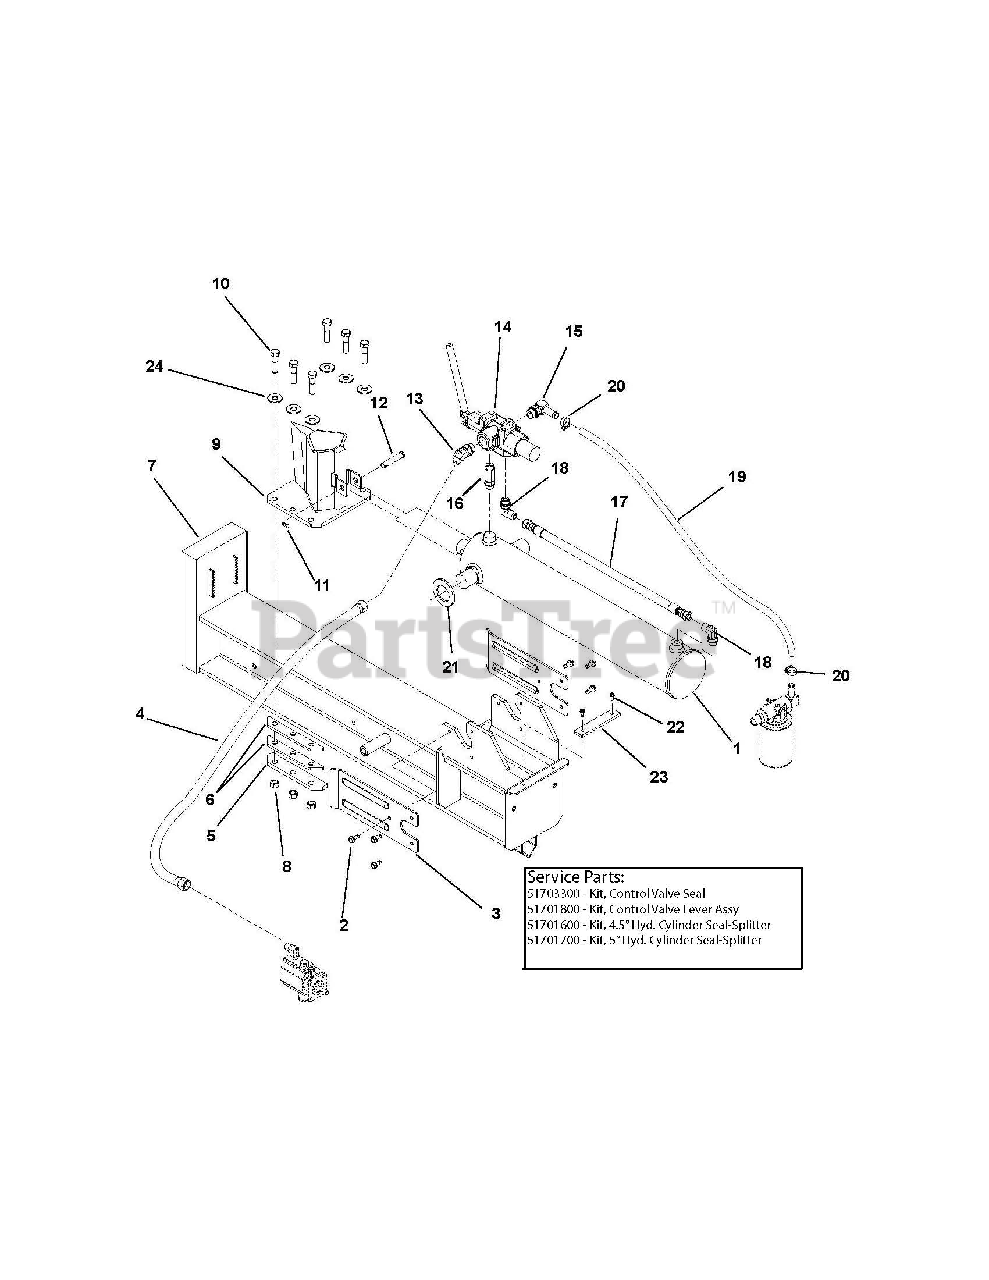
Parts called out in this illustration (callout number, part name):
1	CYLINDER,4.5 W/DECALS
1	KIT,4.5" HYD CYL SEAL-SPLITTER
1	CYLINDER, 5' W/DECALS
1	KIT, 5" HYD CYL SEAL-SPLITTER
2	@SCR-TAP .31-18X.75 HWH TR YWZ
3	PLATE,STRIPPER
4	HOSE, ASM - 46"
5	RETAINER, WEDGE
6	SPACER, WEDGE
7	WLDMT, SPLITTER BEAM
8	@NUT-LK-CTR .50-13 YWZC
9	WEDGE, LOG SPLITTER
10	BLT-HEX .500-13X2.00 GR8 YWZC
11	CLIP, SPRING
12	PIN-CLEV .494X2.50 BRIGHT ZINC
13	FTG,HYD 6802-8-10
14	VALVE CONTROL-SPLITTER
14	KIT,CONTROL VALVE SEAL
14	KIT,CONTROL VALVE LEVER ASSY
15	FTG,HYD 4601-10-10
16	FTG,HYD 6403-NWO-8-8-L
17	HOSE, HYD - 22"
18	FTG,HYD 6801-8-8
19	HOSE,HYD RETURN 10LOLA X 53"
20	CLAMP,.88 DIA. HOSE
21	WSHR-FL-STL 1.57X2.25X.25 YWZC
22	SCR-TAP .25-20X.50 HWH TR YWZ
23	SPACER, CYLINDER
24	@WSHR-FL-STL.563X1.38X.109YWZC
